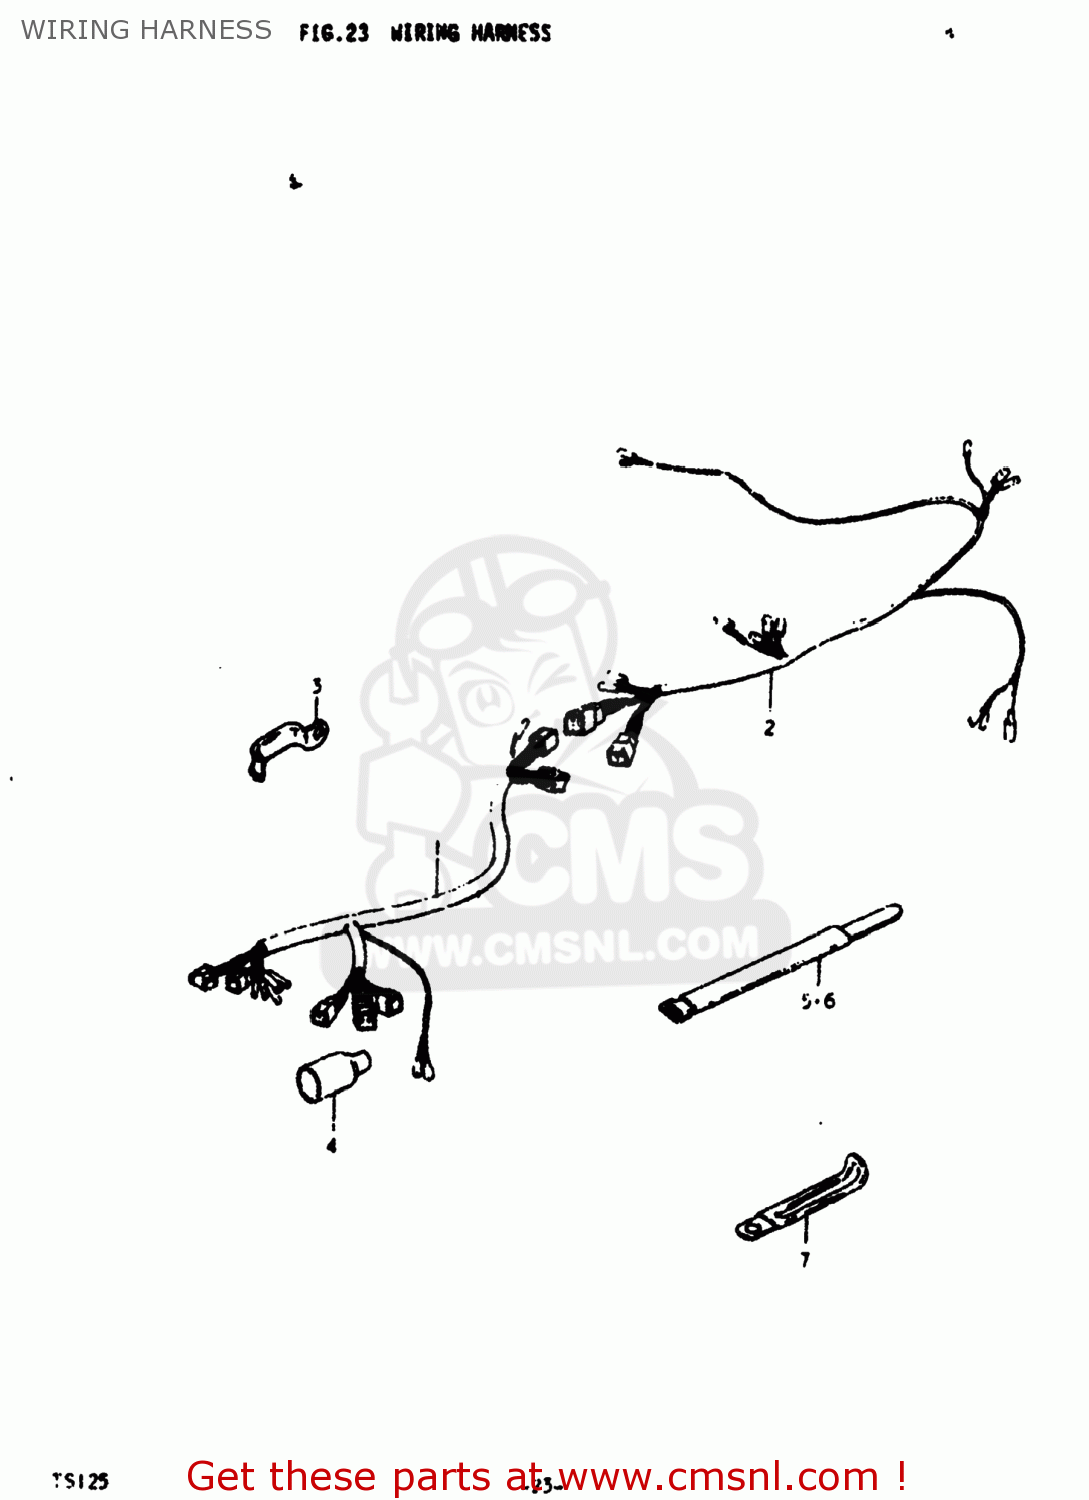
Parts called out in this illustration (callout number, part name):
1	HARNESS,WIRING
2	HARNESS,WIRING NO.2
3	CLAMP
4	BOOT,WIRING HARNESS
5	CLAMP
6	CLAMP(L:250)
7	CLAMP
